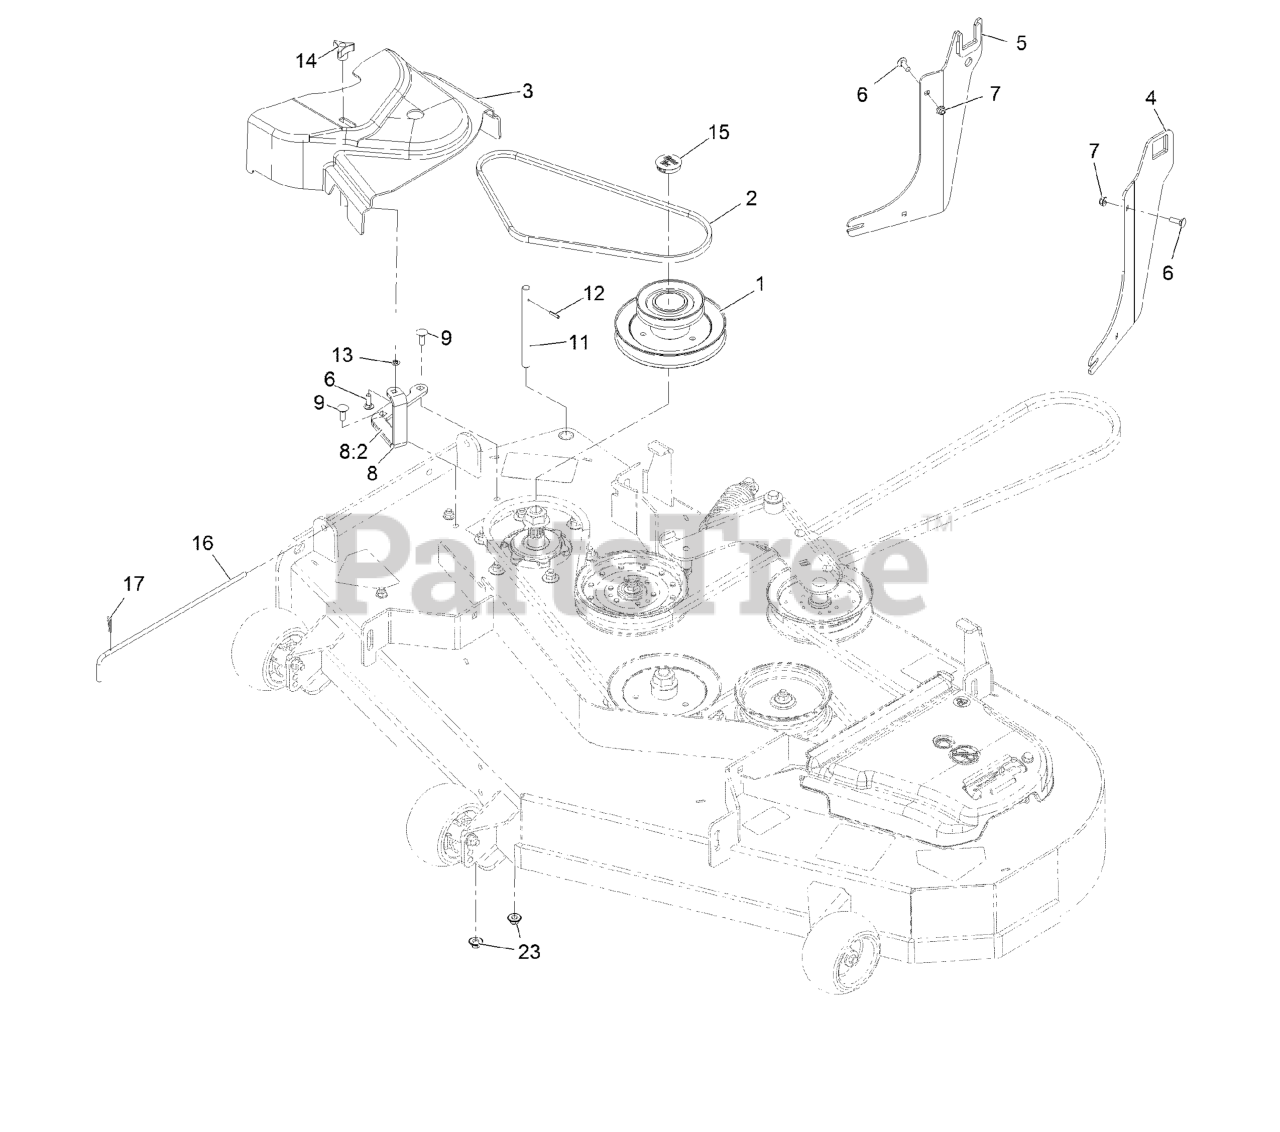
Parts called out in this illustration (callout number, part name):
1	JACKSHAFT-UV DRIVE 52 SPLINED
2	BELT-BLOWER
3	COVER-BELT, UV 52
4	BRACKET ASM, LH
5	BRACKET ASM, RH
6	BOLT-CARR
7	NUT-HF, NI
8	ASM-CVR BRKT W/DECAL
8:2	DECAL-DANGER
9	BOLT-CARR
11	SHAFT-CATCHER, GRASS
12	PIN-ROLL
13	RING-RETAINING, BOLT
14	KNOB-3 PRONG
15	PLUG, BLACK NYLON 1.75
16	PIN,CHUTE PIVOT
17	PIN-COTTER
23	Nut-Nyloc 3/8-16 Flg
